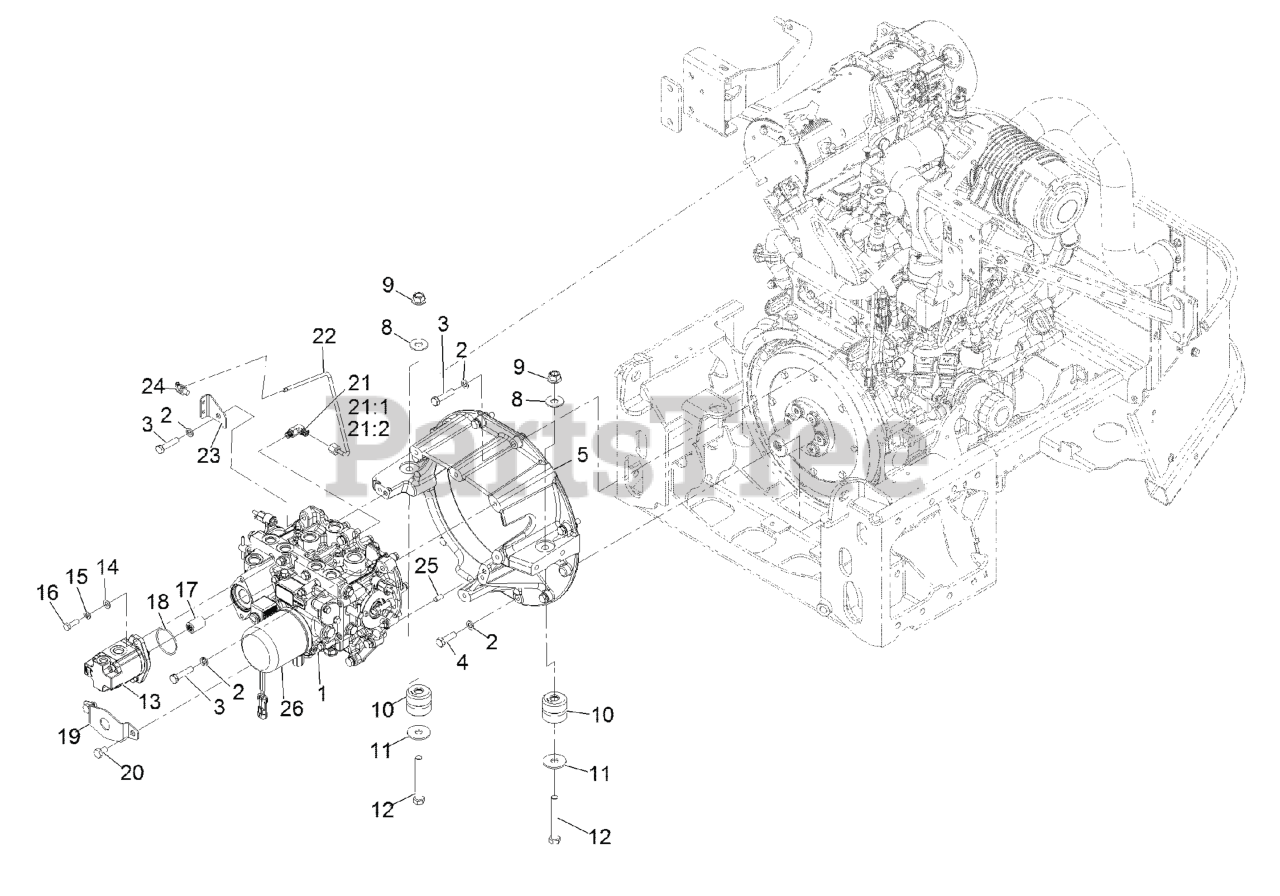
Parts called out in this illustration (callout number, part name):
1	TRANSMISSON ASM
2	WASHER-LOCK
3	SCREW-HH
4	SCREW-HH
5	HOUSING-FLYWHEEL
8	WASHER-FLAT
9	Nut-Lock 1/2-13
10	MOUNT-ISOLATOR
11	WASHER-THRUST
12	SCREW-HH
13	HYD GEAR PUMP ASM
14	WASHER-PLAIN
15	WASHER-LOCK
16	SCREW-HH
17	COUPLER-SPLINE
19	SHIELD-SEAL
20	SCREW-HH
21	FITTING-ELBOW, 90 DEG
21:1	O-RING
21:2	O-RING
22	TUBE ASM
23	SUPPORT-TUBE
24	CLIP-TIE
25	PIN-DOWEL
26	FILTER-OIL, HYD
